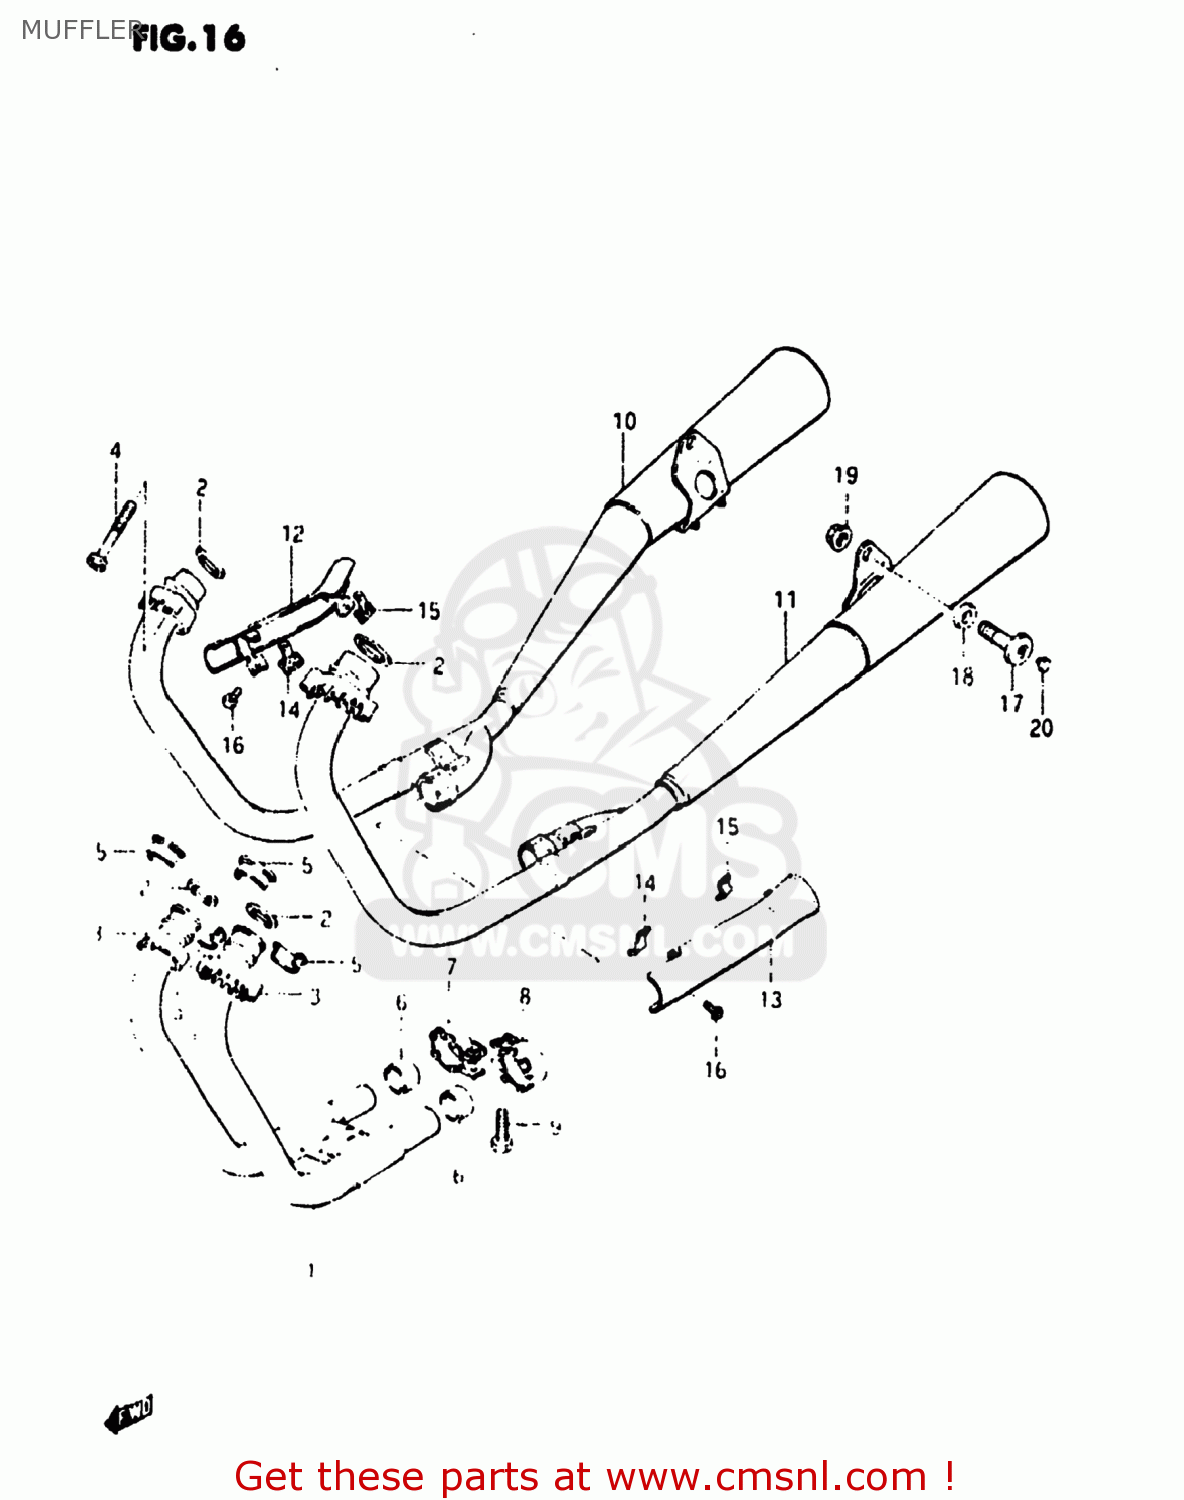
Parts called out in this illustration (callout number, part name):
1	PIPE,EXHAUST,CENTER
2	GASKET,EXHAUST PIPE (NAS)
3	CLAMP(H:21)
4	BOLT
5	PLATE,EXHAUST
6	CONNECTOR,MUFFLER
7	CLAMP,MUFFLER CONNECTOR
8	CLAMP,MUFFLER CONNECTOR
9	BOLT
10	MUFFLER ASSEMBLY
11	MUFFLER ASSEMBLY
12	COVER,MUFFLER,RIGHT
13	COVER,MUFFLER,LEFT
14	CLAMP,MUFFLER COVER
15	CLAMP,MUFFLER COVER
16	SCREW
17	BOLT
18	WASHER(10.5X20X3.2)
19	NUT
20	CAP
